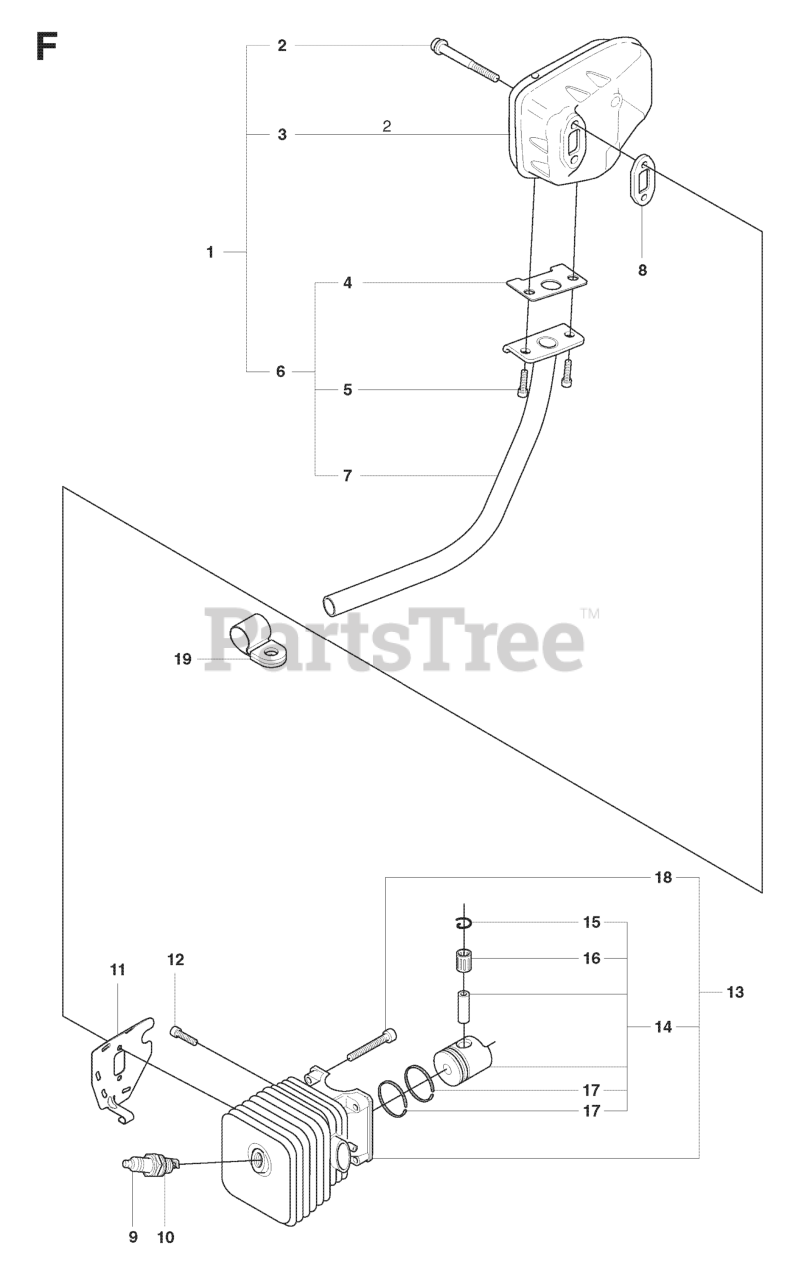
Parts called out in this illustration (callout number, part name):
4	GASKET EXHAUST PIPE
9	SPARK PLUG RCJ7Y
10	SPARK PLUG M14X1.25 NGK BPMR7A
11	AIR CONDUCTOR
12	SCREW M5X14
17	PISTON RING
18	SCREW MC6S 5X35
